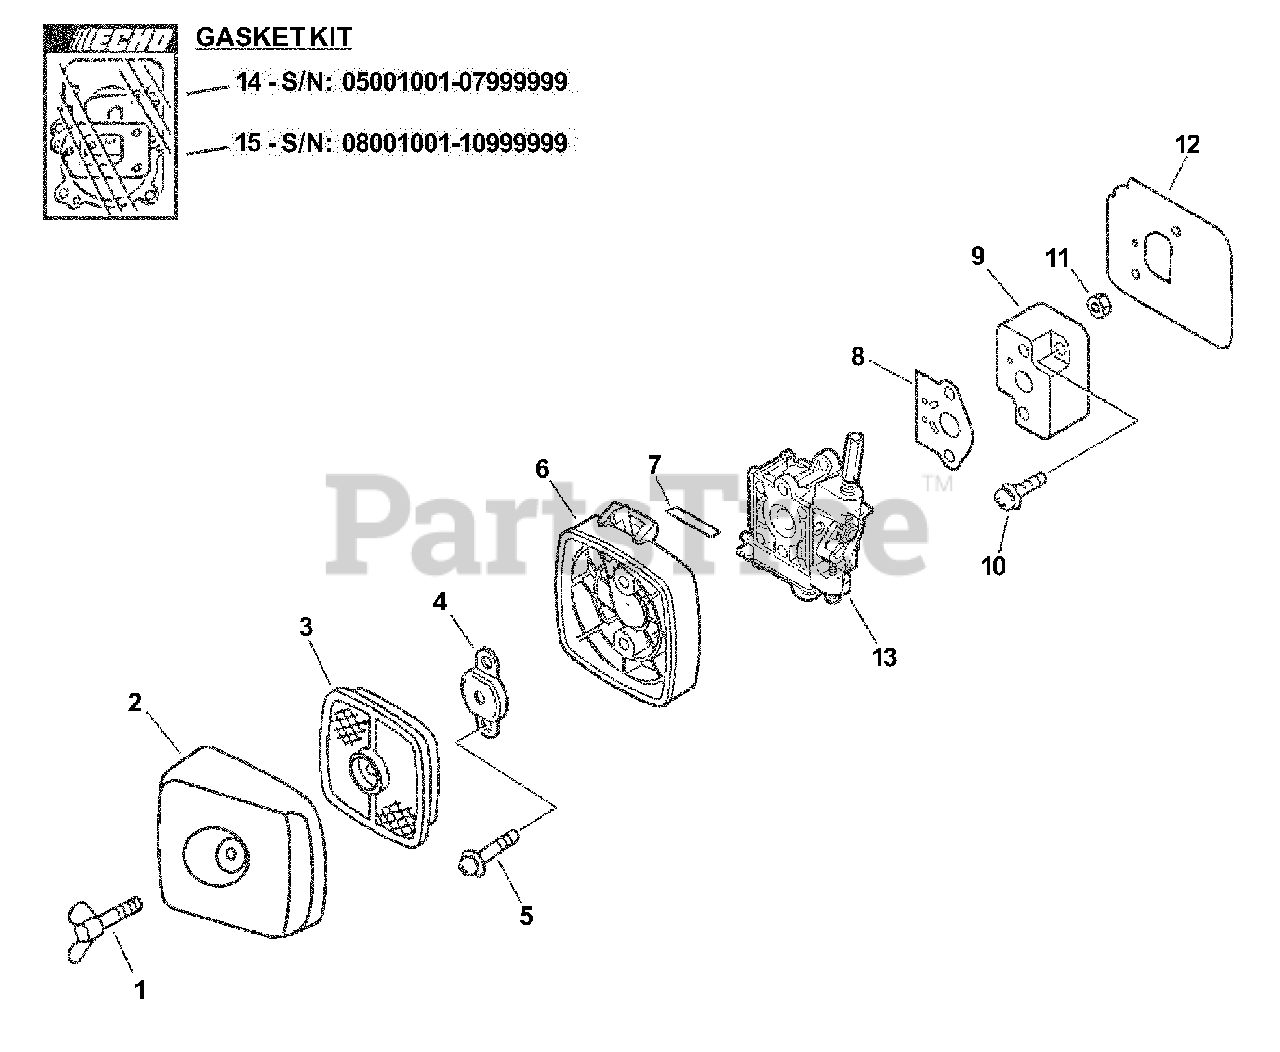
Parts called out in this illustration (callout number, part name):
1	THUMBSCREW
2	COVER, AIR FILTER - GRAY
3	FILTER, AIR - SINGLE LAYER
4	PLATE, PREVENT
5	SCREW - 5X65
6	CASE, AIR FILTER - GRAY
7	LABEL - CHOKE
8	GASKET, INTAKE
9	INSULATOR, INTAKE
10	SCREW - 5X20
12	SHIELD, INTAKE
13	CARBURETOR
14	GASKET KIT
15	GASKET KIT
